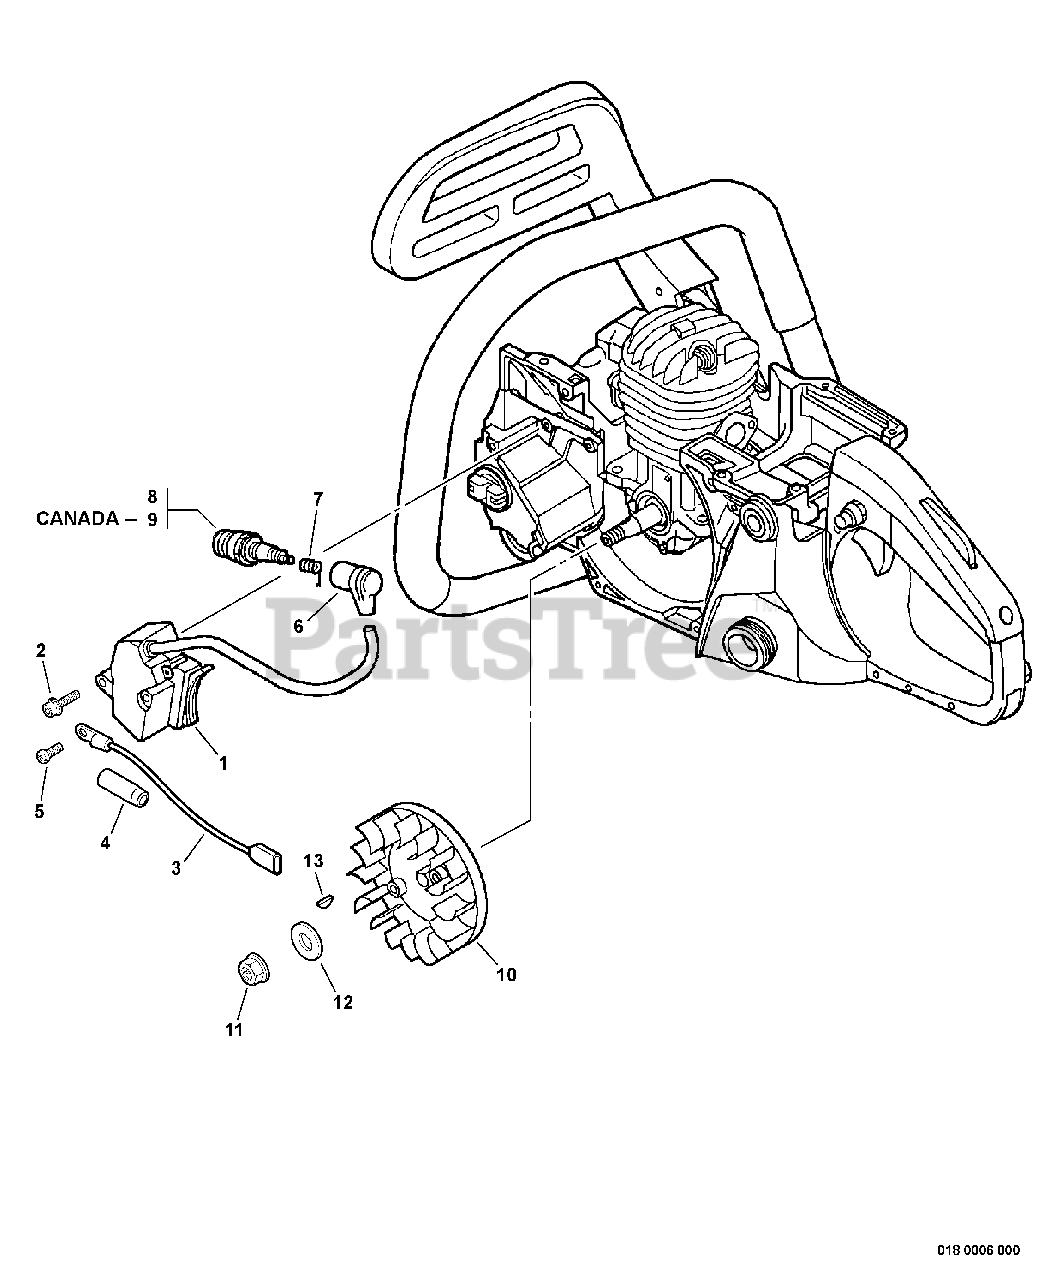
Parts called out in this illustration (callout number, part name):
1	COIL, IGNITION
2	BOLT 4×30
3	LEAD - GROUND
4	BOOT, CONNECTOR
5	SCREW 4×6
6	CAP, SPARK PLUG
7	TERMINAL, SPARK PLUG
8	SPARK PLUG - BPM8Y
9	SPARK PLUG - BPMR8Y
10	FLYWHEEL
12	WASHER, SPRING 8
13	KEY, WOODRUFF
